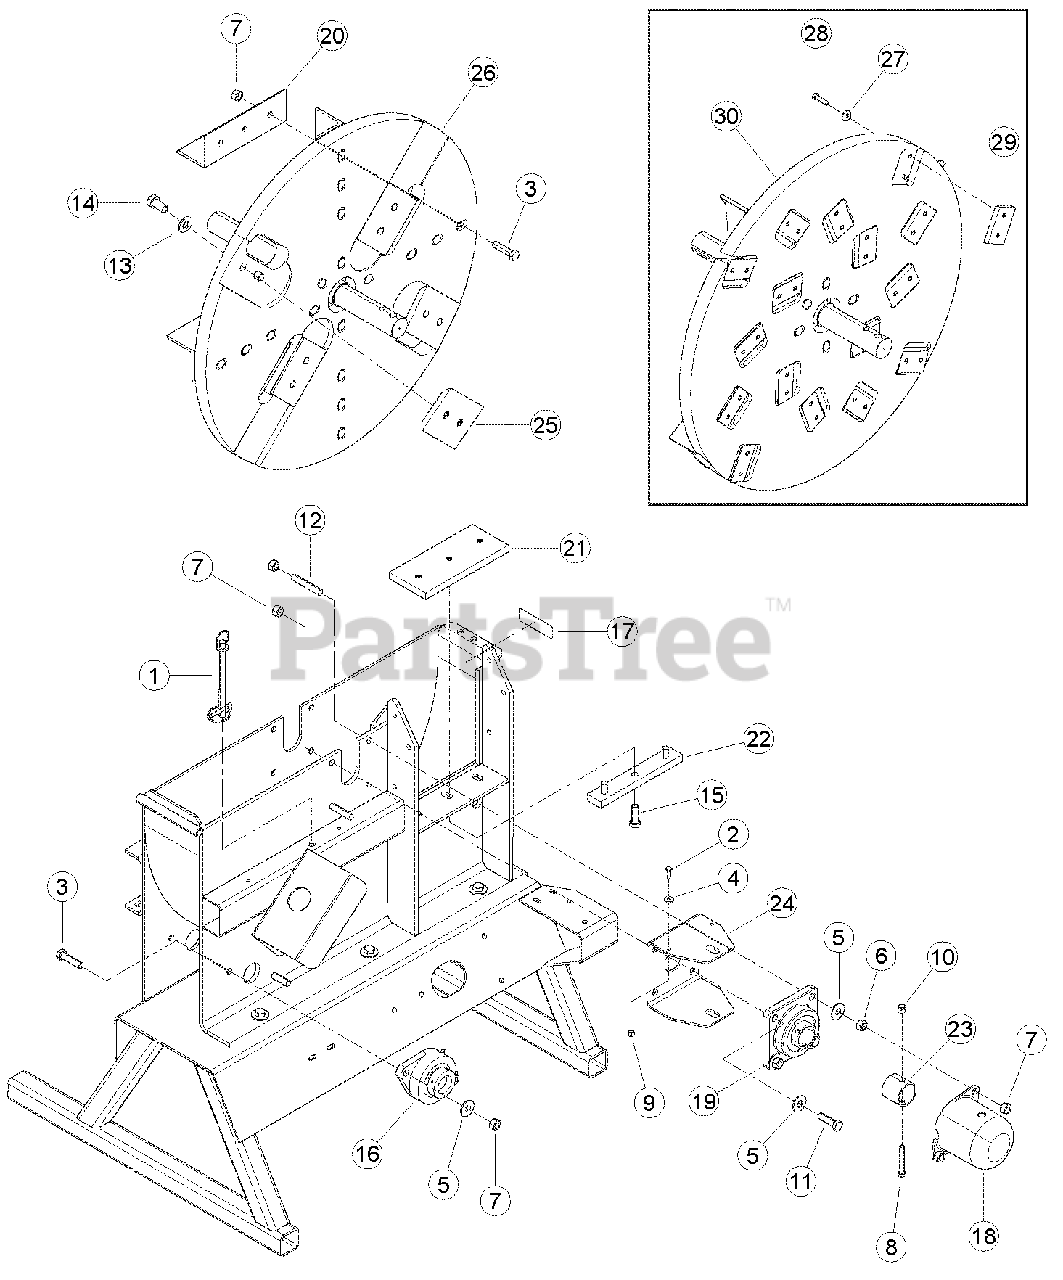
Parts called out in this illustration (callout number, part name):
1	PIN, HITCH 1/2 X 6-1/2 W/LYNCH
2	BOLT, 1/4 X 3/4 HEX HD GR5 ZP
3	BOLT, 1/2 X 2 HEX HD GR5 ZP
4	WASHER, 1/4 FLAT ZP
5	WASHER, 1/2 FLAT ZP
6	NUT, 1/2 HEX NC ZP
7	NUT, 1/2 CENTERLOCK GRB ZP
8	BOLT, 3/8 X 2-1/2 HEX HD GR5 ZP
9	NUT, 1/4 NE NYLOCK ZP
10	NUT, 3/8 NE NYLOCK ZP
11	BOLT, 1/2 X 1-3/4 HEX HD GR5 NC ZP
12	STUD, 1/2-13 X 3 LONG B7 ZP
13	WASHER, 5/8 SAE HARDENED
14	BOLT, M16 X 2.0 X 30 HEX HD W/PATCH
15	BOLT, 1/2 X 1-1/2 HEX HD GR8 NC ZP
16	BEARING, 2 BOLT FLANGE 1-1/2" BORE
17	DECAL, SERIAL NUMBER
18	CAP, LARGE SHAFT
19	BEARING, 4 BOLT FLANGE 1-3/4" BORE
20	PADDLE, BIG CHIPPER
21	PLATE, CHIPPER BOTTOM
22	SPACER, CHIPPER ANVIL
23	COLLAR, CHIPPER LOCK
24	BRACKET, DISK LOCK
25	KIT, CHIPPER BLADE
26	ASSEMBLY, 9 INCH CHIPPER DISK
27	WASHER, 5/16 GR8 USS FLAT
28	BOLT, 5/16 X 1-1/4 HEX HD GR8 PATCH
30	ASSEMBLY, CHIPPER DISK
